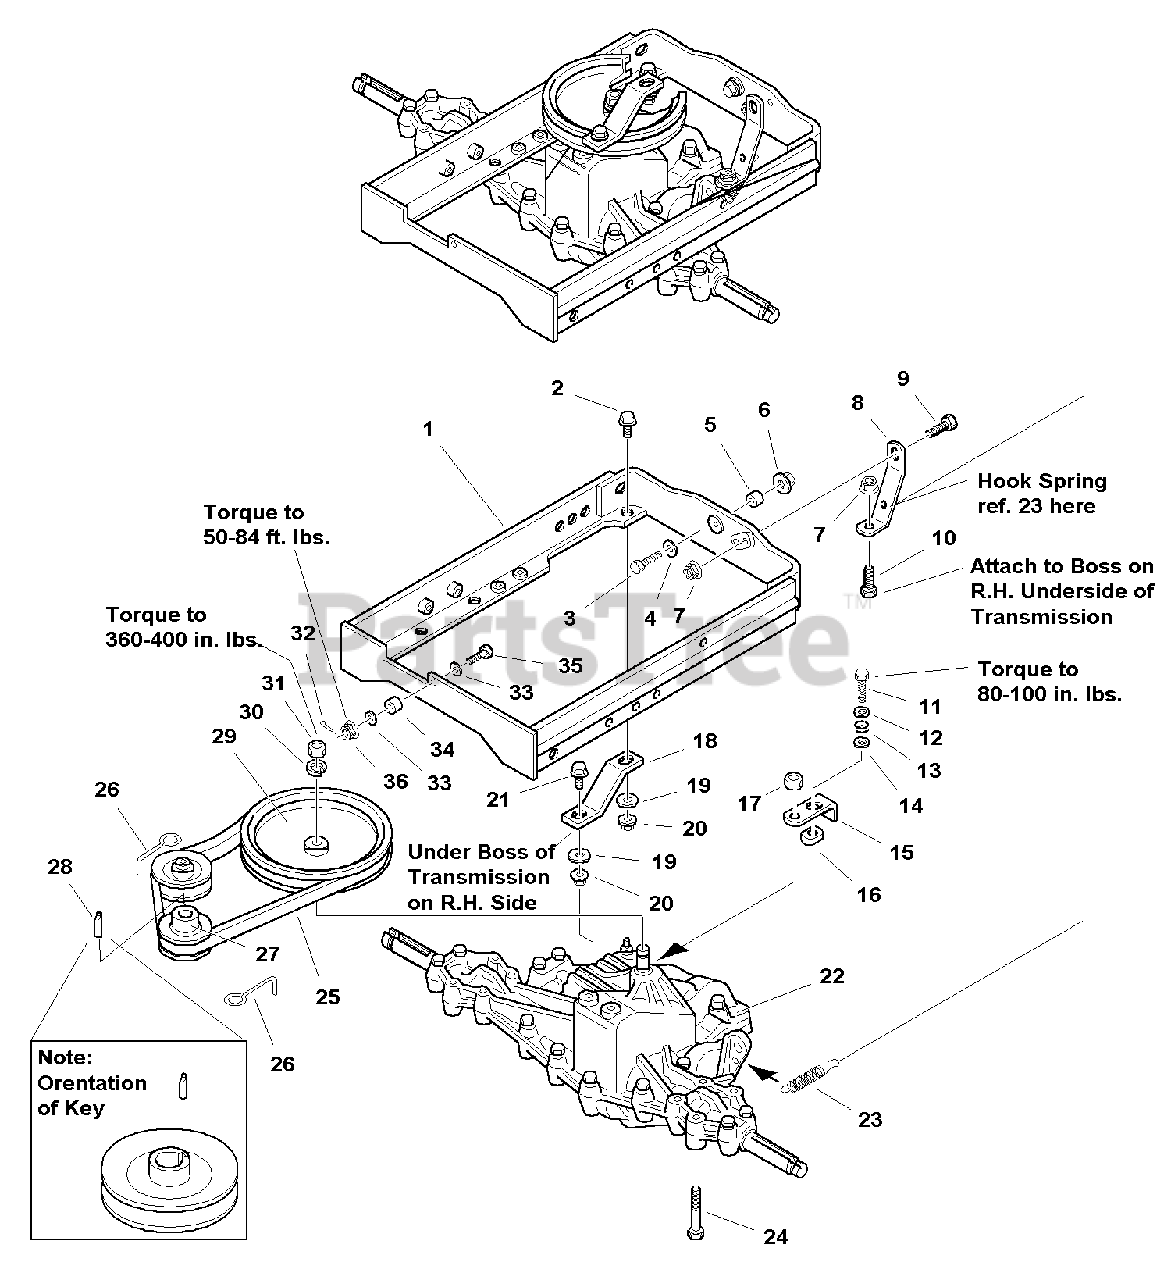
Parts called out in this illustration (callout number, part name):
1	CARRIER ASSEMBLY
2	CAPSCREW, Hex Head, Whizlock, 5/16-18 x 3/4
3	CAPSCREW, Hex Head, 1/2-13 x 1-1/4
4	WASHER, Plain, 17/32 x 1-1/4 x 5/64
6	NUT, Hex, Flange Lock, 1/2 x 13
7	NUT, Hex, Flange Whizlock, 5/16-18
8	STRAP, Torque
9	CARRIAGE BOLT, 5/16-18 x 5/8
10	CAPSCREW, Hex, 5/16-18 x 2-1/4
11	CAPSCREW, Taptite, #10-24 x 1-1/4
12	WASHER, 1/4
14	WASHER, Plain, 13/32 x 1-1/4 x 1/16
15	LEVER, Release
17	NUT, Hex, Lock, 1/4-20
18	STRAP, Torque
19	WASHER, 5/16
20	NUT, Hex, Flange Lock, 5/16-18
21	CAPSCREW, Hex, Whizlock, 5/16-18 x 1-1/2
22	* TRANSMISSION, Hydro (HydroGear, Mod 311-0500)
23	SPRING, Return
24	CAPSCREW, Taptite, 5/16-18 x 2-1/4
27	PULLEY, Engine
28	KEY, Hi-Pro
29	PULLEY, Transmission
30	LOCKWASHER, 1/2
31	NUT, Hex, Jam, 1/2-20
32	COTTER PIN, 1/8 x 1-1/2
33	WASHER, Belleville, 1/2
35	CAPSCREW, Hex Head, With Hole, 1/2-20 x 1-3/4
36	NUT, Hex, Slotted, 1/2-20
